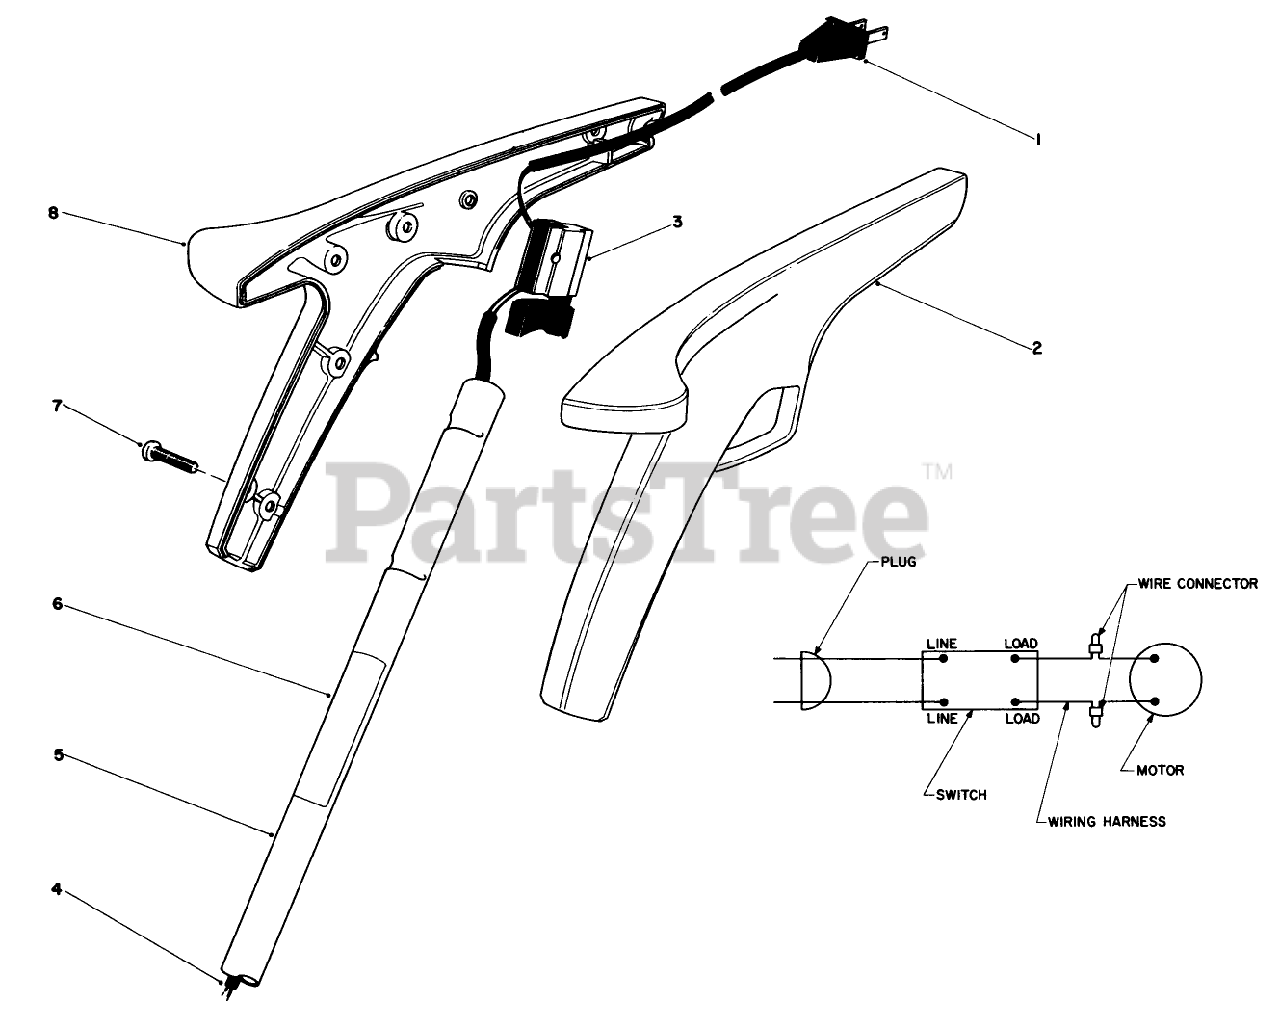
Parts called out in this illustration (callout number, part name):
1	Power Cord
2	L.H. GRIP
3	SWITCH SINGLE SPEED
4	WIRING HARNESS
6	REP. SERIAL PLT
7	#8 X .625" PHILPS PAN H
8	Grip-Right Hand
